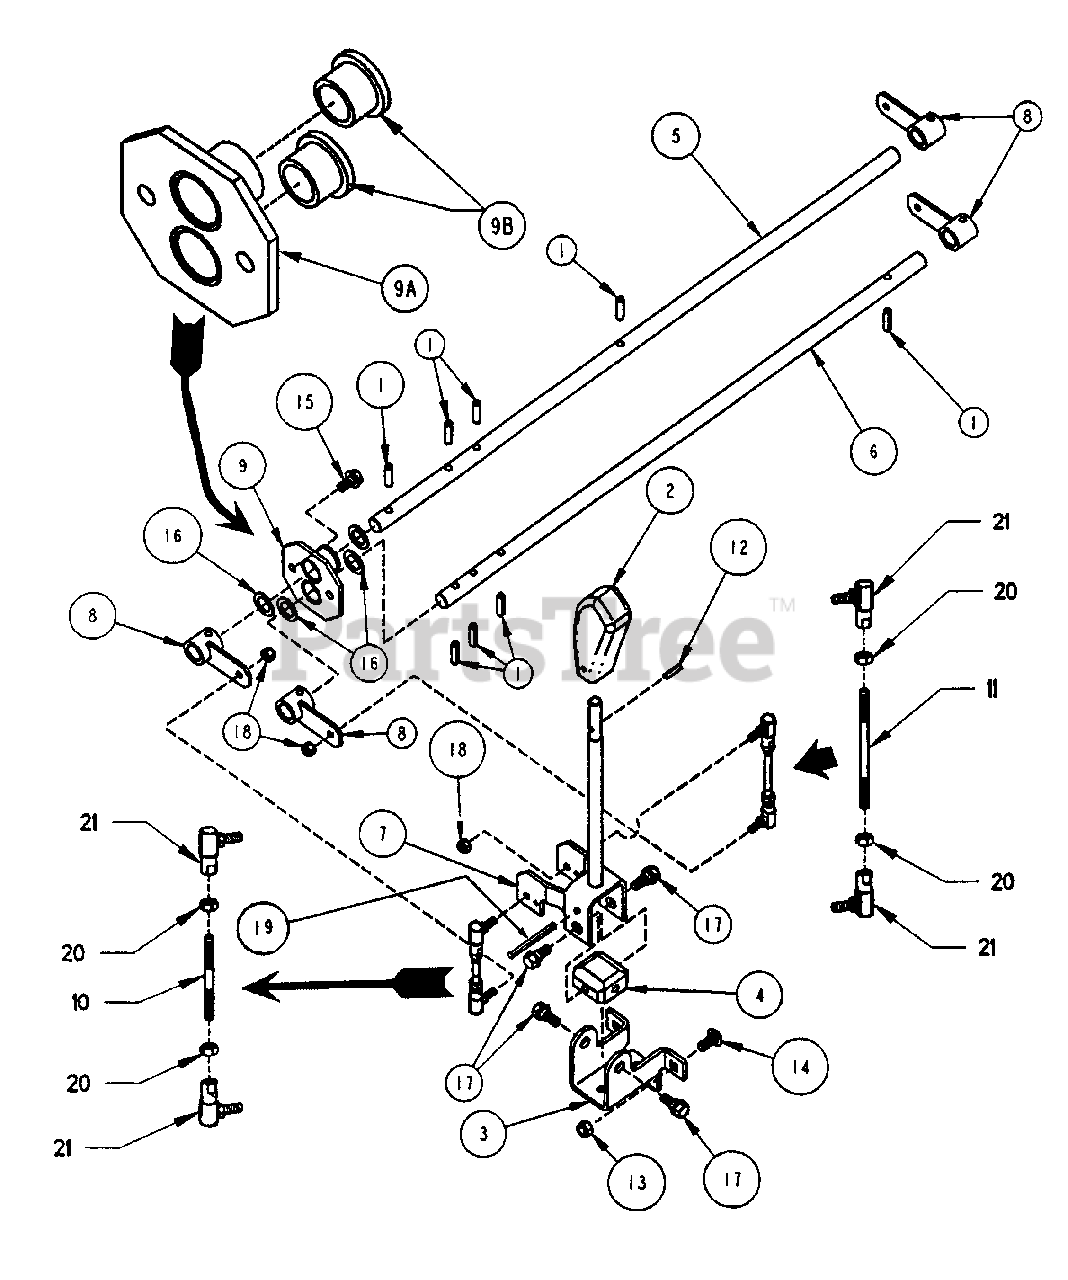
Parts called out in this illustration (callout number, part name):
1	ROLL PIN, 1/4 x 1"
2	HANDLE, Plastic
3	BRACKET, Joystick Mounting
4	BLOCK, Pivot Joystick Control
5	SHAFT, Upper Cross
6	SHAFT, Lower Cross
7	HANDLE, Joystick Control (Weldment)
8	ARM/HUB Weldment
9	ASSEMBLY, Cross Shaft Support
9A	SUPPORT, Cross Shaft (Weldment)
10	ROD, Threaded 1/4-28 x 2.71 long
11	ROD, Threaded 1/4-28 x 3.85 long
12	ROLL PIN 3/16 x 3/4"
13	NUT, 5/16-18 HEX NYLON LOCK
14	BOLT, 5/16-18 x 3/4" Sq.Nk. Carriage, Grade 5
15	SCREW, 5/16-18 x 5/8" Hex Washer Self-Tap
16	WASHER, 41/64 I.D. x 1" O.D. Flat
17	BOLT, 5/16-18 Shoulder
18	NUT, 1/4-28 Hex Nyloc
19	ROLL PIN, 1/4 x 2-3/4"
20	HN, 1/4F GR5 YZ
21	BALL-JOINT
